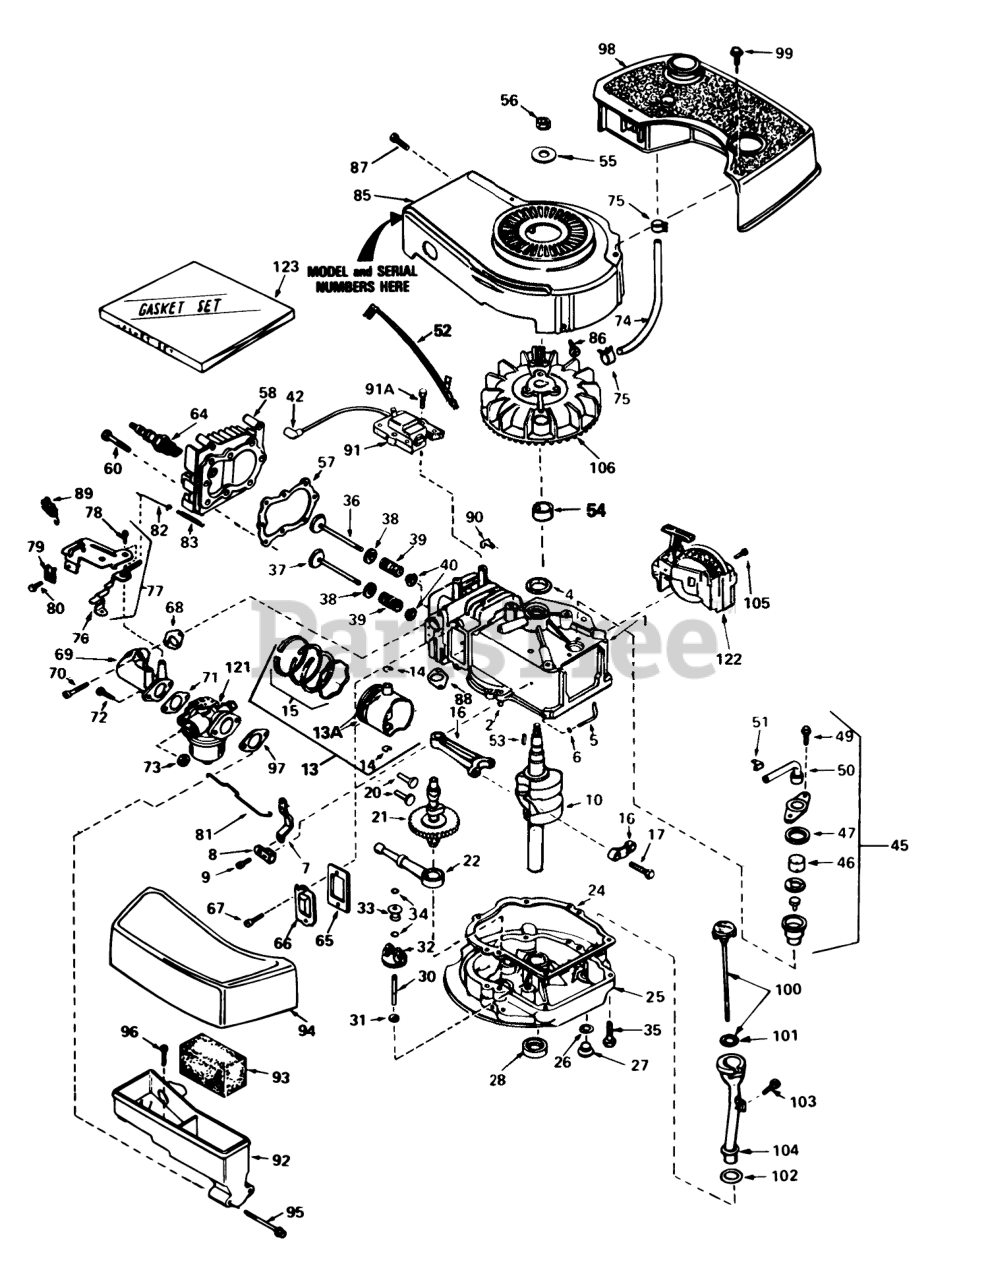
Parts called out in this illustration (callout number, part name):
1	Cylinder Assy. (Incl. #2 & 4)
2	Pin-Dowel
4	Seal-Oil
5	Rod, Governor (Incl. #6)
6	Washer-Flat
7	Governor Lever
8	Clamp-Lever, Governor
9	Screw
10	Crankshaft
13	Piston, Pin & Ring Assy. (Std.) (Incl. #13A, 14 & 15)
13	Piston, Pin & Ring Assy. (.010 O.S.)(Incl. #13A, 14 & 15)
13	Piston, Pin & Ring Assy.(.020 oversize) (Incl. #13A, 14 & 15)
13A	Piston & Pin Assy. (Std.) (Incl. #14)
13A	Piston & Pin Assy. (.010 over size) (Incl. #14)
13A	Piston & Pin Assy. (.020 over size) (Incl. #14)
14	Ring-Retaining, Piston Pin
15	Ring Set (Std.)
15	Ring Set (.020" OS)
15	Ring Set (.010" OS)
16	Rod Assy., Connecting (Incl. #17)
17	Bolt-Rod, Connecting
20	Lifter-Valve
21	Camshaft(Mech.Comp. Release)
22	Oil Pump ASM
24	Gasket, Mounting
25	Flange Assy., Mounting (Incl. #26 thru 30)
26	Gasket-Oil Drain
27	Plug Oil Drain
28	Seal Oil
30	Shaft-Governor
31	Washer-Flat
32	Gear Assy., Governor (Incl. #31 )
33	Spool-Governor
34	Ring-Retaining
35	Screw (1/4-20 x 1-1/4)
36	Valve, Intake (Std.) (Incl. #40)
36	Valve, Intake (1/32" oversize) (Incl. #40)
37	Valve, Exhaust (Std.) (Incl. #40)
37	Valve, Exhaust (1/32" oversize (Incl. #40)
38	Cap-Upper Valve Spring
39	Spring-Valve
40	Cap-Valve, Spring
42	Cover-Spark Plug
45	Breather Assy. (Incl. #46 thru 51)
46	Element-Breather
47	Gasket-Breather
49	Screw (10-24 x 9/16)
50	Tube, Breaker
51	Clip, Breather
52	Wire-Ground
53	Key-Flywheel
55	Washer-Belleville
56	Nut-Flywheel
57	63573 GIL 42 SNWTHW
58	Head-Cylinder
60	Screw (5/16-18x1-1/2)
64	Plug, Spark (J17LM or equiv.)
64	Plug, Spark (Champion RCJ-8)
65	Gasket-Breather
66	Cover-Valve
68	Gasket-Intake
69	Pipe, Intake (Incl. #68)
70	Screw (1/4-20 x 1)
71	Gasket-Carburetor
72	Screw (1/4-28 x 7/8)
73	Nut and Lock Washer (1/4-28)
74	Line-Fuel
75	Clamp-Line, Fuel
76	Lever Control
77	Control Assy., Speed (Incl. #76, 78 & 89)
78	Screw, Hex Washer Hd Shoulder Self-Tap
79	Conduit
80	Screw (10-32 x 3/8)
81	Link-Throttle
82	Link Governor Spring
83	Spring Governor
85	Housing-Blower
86	Screw (1/4-20x19/32)
87	Screw (10-24 x 9/16)
88	Gasket Exhaust
89	Terminal
90	Clip-Wire
91	Lamination & Coil Assy. (Solid State) (Incl. #42)
91A	Screw
92	Body Air Cleaner
93	Filer, Air
94	Cove, Air Cleaner
95	Screw Fil Hd.
96	Screw, Hex Hd.
97	Gasket-Air Cleaner
98	Tank-Fuel
99	Screw (10-32 x 35/64)
100	Dipstick, Oil (Incl. #101)
103	Screw (10-32 x 1/2)
104	Tube-Oil Fill
105	Screw (1/2-20x5/8)
106	Flywheel
121	Carburetor (Incl. #71)
122	Starter-Sidemount
123	Gasket Set (Incl. items marked )
